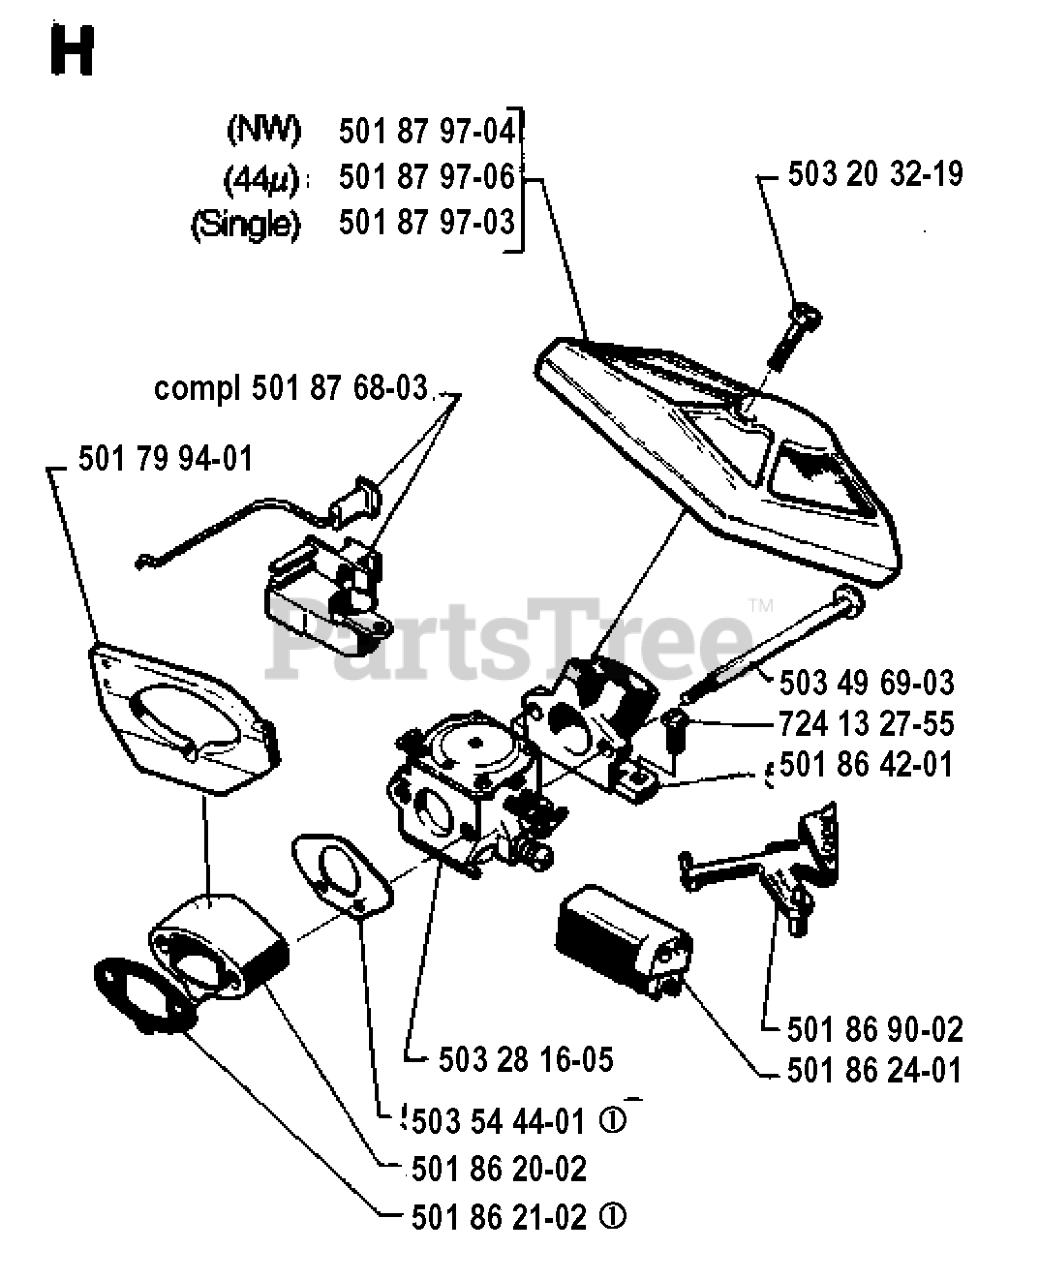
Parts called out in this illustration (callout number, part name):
1	DECAL.FENDER.WARNING.ENG
2	DECAL.WARN.RESERVE.FUEL
4	DECAL, WARNING SPARK ARRESTOR
5	DECAL.MOWER
6	DECAL, ENGINE
8	DECAL.MOWER.SCH.48/54
9	DECAL BTRY SYMBOLS
14	DECAL, PANEL SD
15	DECAL.WARNING.CUST.RESP.E85.
16	RP.DECAL.BADGE.170MM.TEXTLOGO
17	DECAL.RP.BSM44
